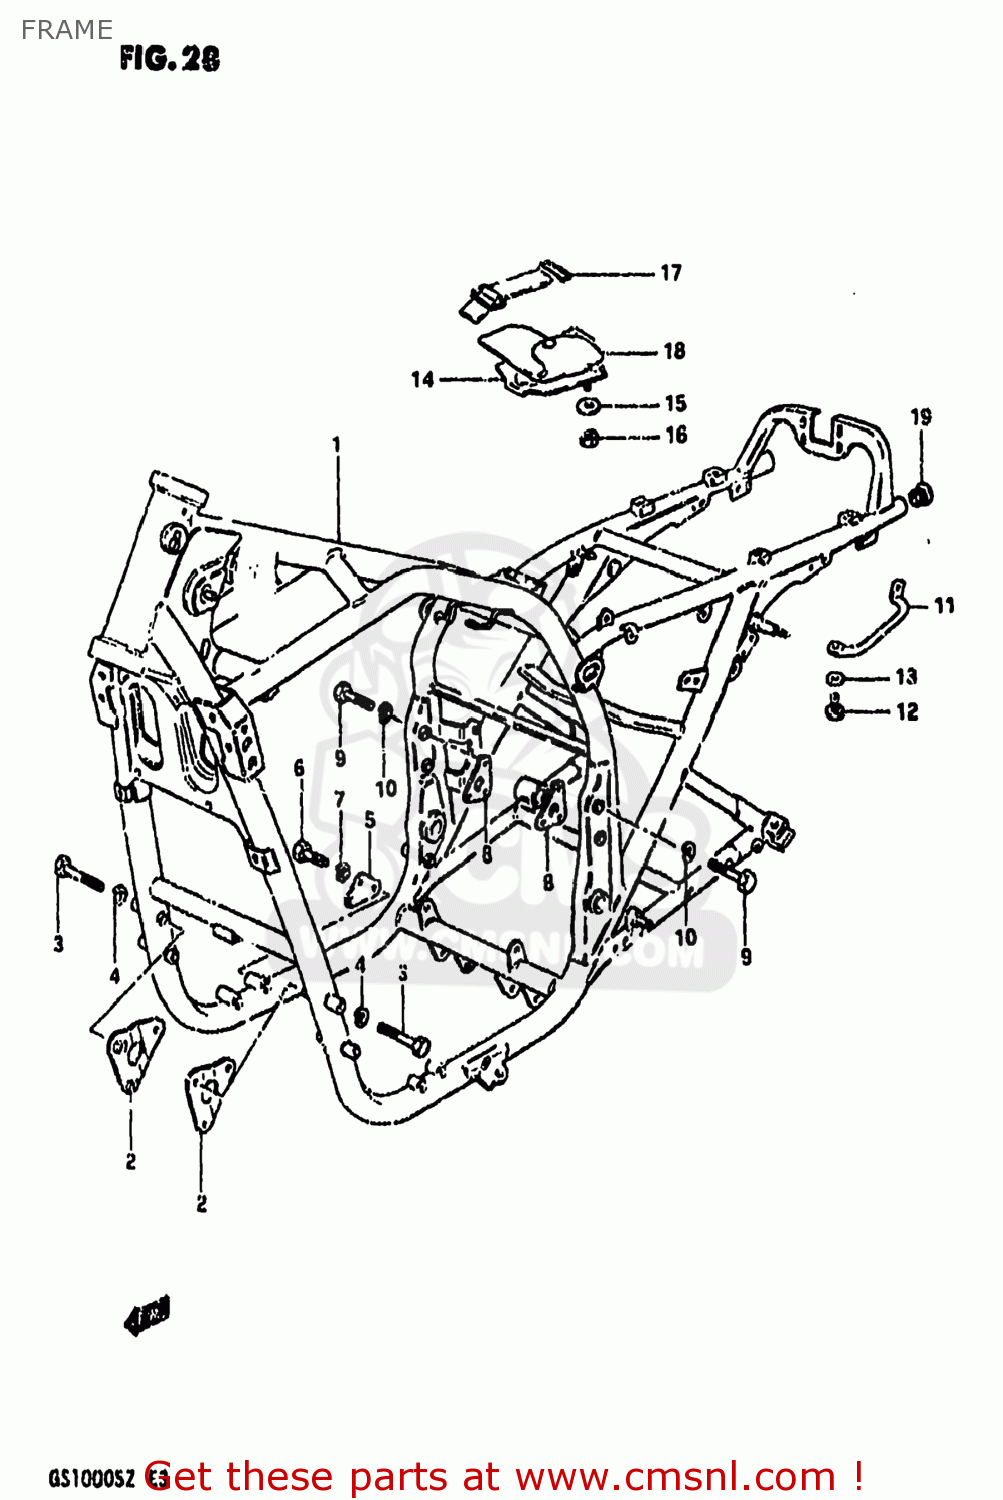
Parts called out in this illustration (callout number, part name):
1	FRAME (SILVER)
2	PLATE,ENGINE MOUNTING
3	BOLT(8X65)
4	LOCK WASHER
5	PLATE,ENG MTG NO.2
6	BOLT 8X16
7	LOCK WASHER
8	PLATE,ENG MTG NO.4
9	BOLT
10	LOCK WASHER
11	GRIP,STAND
12	BOLT
13	WASHER
14	HOLDER,TOOL
15	WASHER(6.5X30X1.6)
16	NUT
17	BAND
18	TOOL SET
19	CAP(OD:26)
